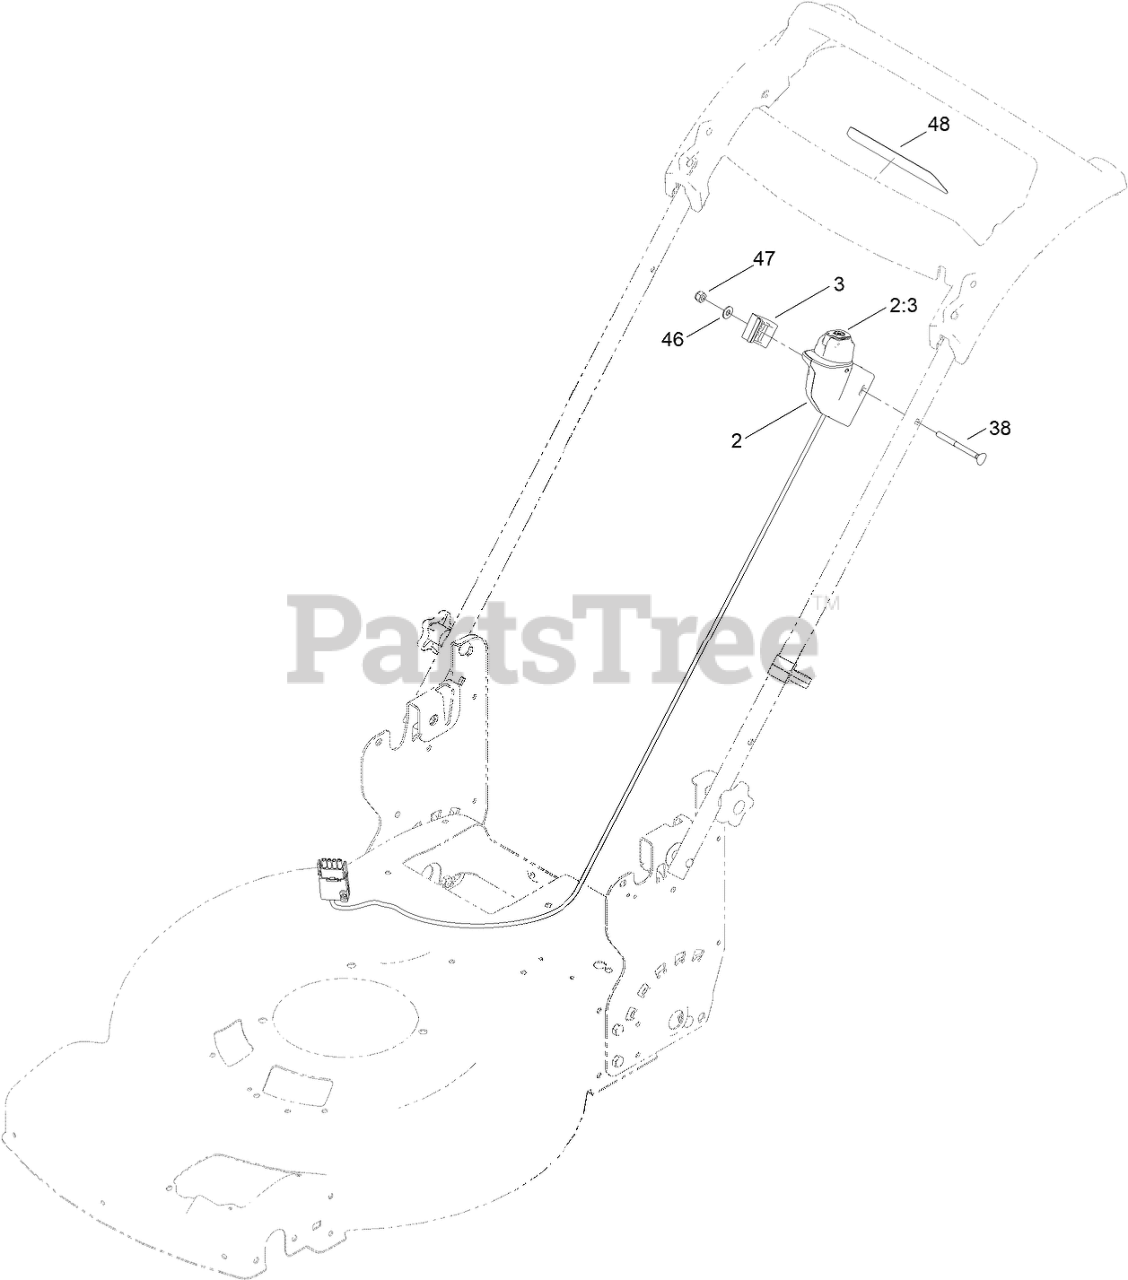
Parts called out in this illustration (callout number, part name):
2	SWITCH-STARTER ASM
2:3	STARTER BUTTON SERVICE ASM
3	CLAMP-CABLE
38	SCREW-HANDLE
46	WASHER-FLAT
47	NUT-LOCK, NI
48	DECAL-CONTROLS (60V, START)
